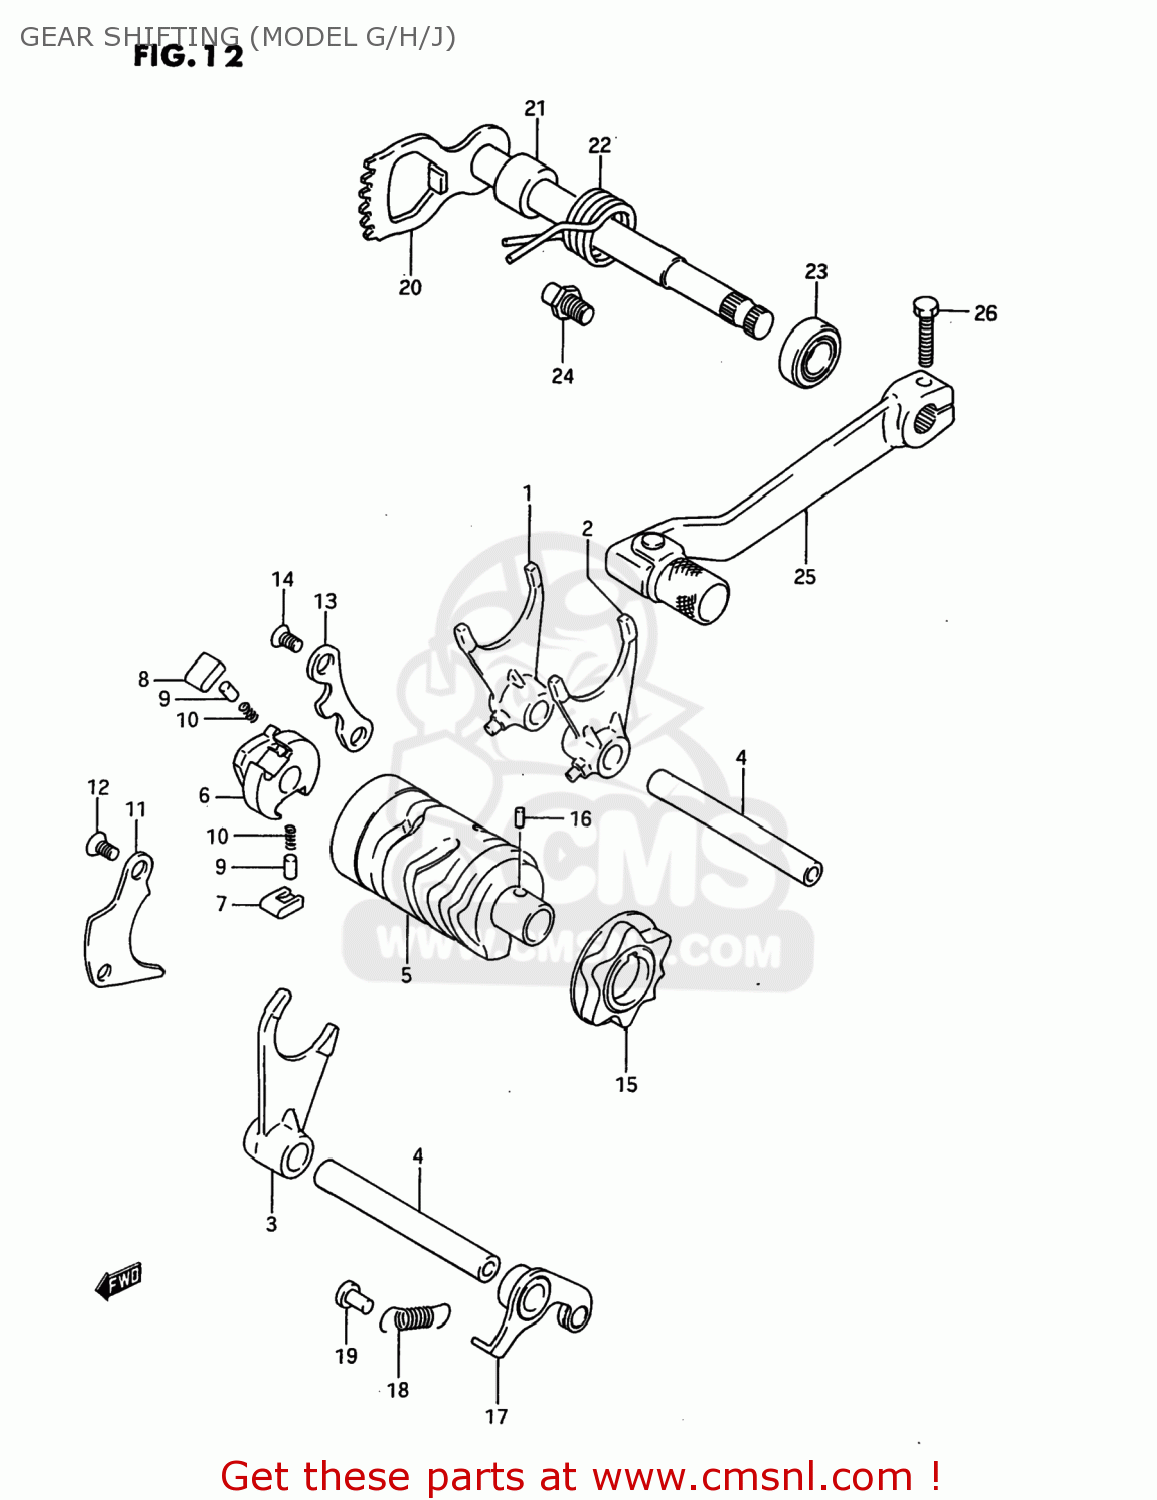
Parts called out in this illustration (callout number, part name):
1	FORK,GEAR SHIFT NO.1
2	FORK,GEAR SHIFT NO.2
3	FORK,GEAR SHIFT NO.3
4	SHAFT,GEAR SHIFT FORK
5	CAM,GEAR SHIFT
6	GEAR,GEARSHIFT CAM DRIVE
7	PAWL,GEAR SHIFT NO.1
8	PAWL,GEAR SHIFT NO.2
9	PIN(5X8)
10	SPRING
11	LIFTER,GEAR SHIFT PAWL
12	SCREW
13	GUIDE,GEAR SHIFTING CABLE
14	SCREW
15	PLATE,GEAR SHIFT CAM STOPPER
16	PIN
17	STOPPER,GEAR SHIFTING
18	SPRING
19	RIVET
20	SHAFT,GEAR SHIFT
21	SPACER(12X20X15.3)
22	SPRING
23	OIL SEAL
24	STOPPER,GEAR SHIFT CAM
25	LEVER ASSY,GEAR SHIFT
26	BOLT
